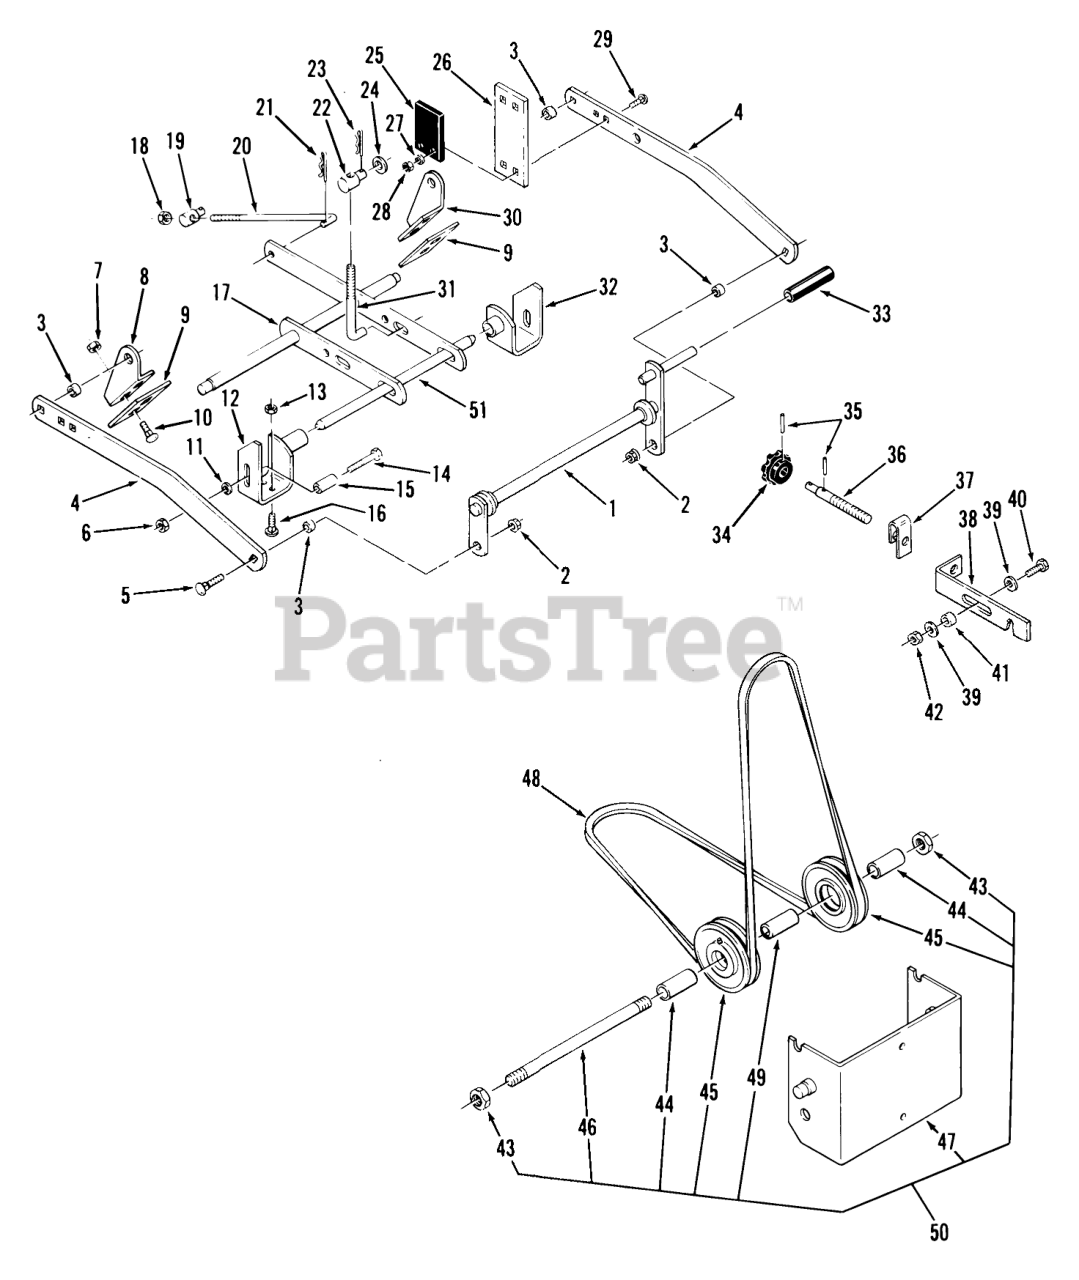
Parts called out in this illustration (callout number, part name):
1	Hitch Assy.
2	LOCKNUT-FLANGE
3	SPACER
4	Bar Draft
5	Bolt
6	Nut
7	Nut
8	Bracket-R.H.
9	PLATE
10	Bolt
11	WASHER
12	ASSY-FRT DK BKT R R
13	Nut
14	7/16-14X13/4 HEX BLT
15	SPACER-BEARING
16	Bolt-Carriage
17	Leveler Ass-y.
18	NUT
19	TRUNNION-LIFT
20	ROD-LEVELER
21	Hairpin
22	ROD-TRUNNION LIFT
23	Hairpin Cotter
24	Washer
25	BUMPER
26	PLATE-BUMPER R
27	Collar
28	Nut
29	Bolt-Carriage
30	Bracket-L.H.
31	LIFT ROD
32	LH FT DECK BRKT A R
33	GRIP
34	KNOB-ADJUSTMENT
35	PIN-ROLL
36	HITCH ADJ SCREW
37	Detent Spring
38	Hitch Adjustment Link
39	Washer
40	Bolt
41	SPACER
42	Nut
43	Nut
44	SPACER FRONT PULL R
45	Pulley-V
46	SHAFT FRONT PULLEY
47	Shield Assy.
48	V BELT
49	SPACER-FRONT PULLEY
50	S.A. Front Idler-Complete
51	SHAFT-FRONT R
